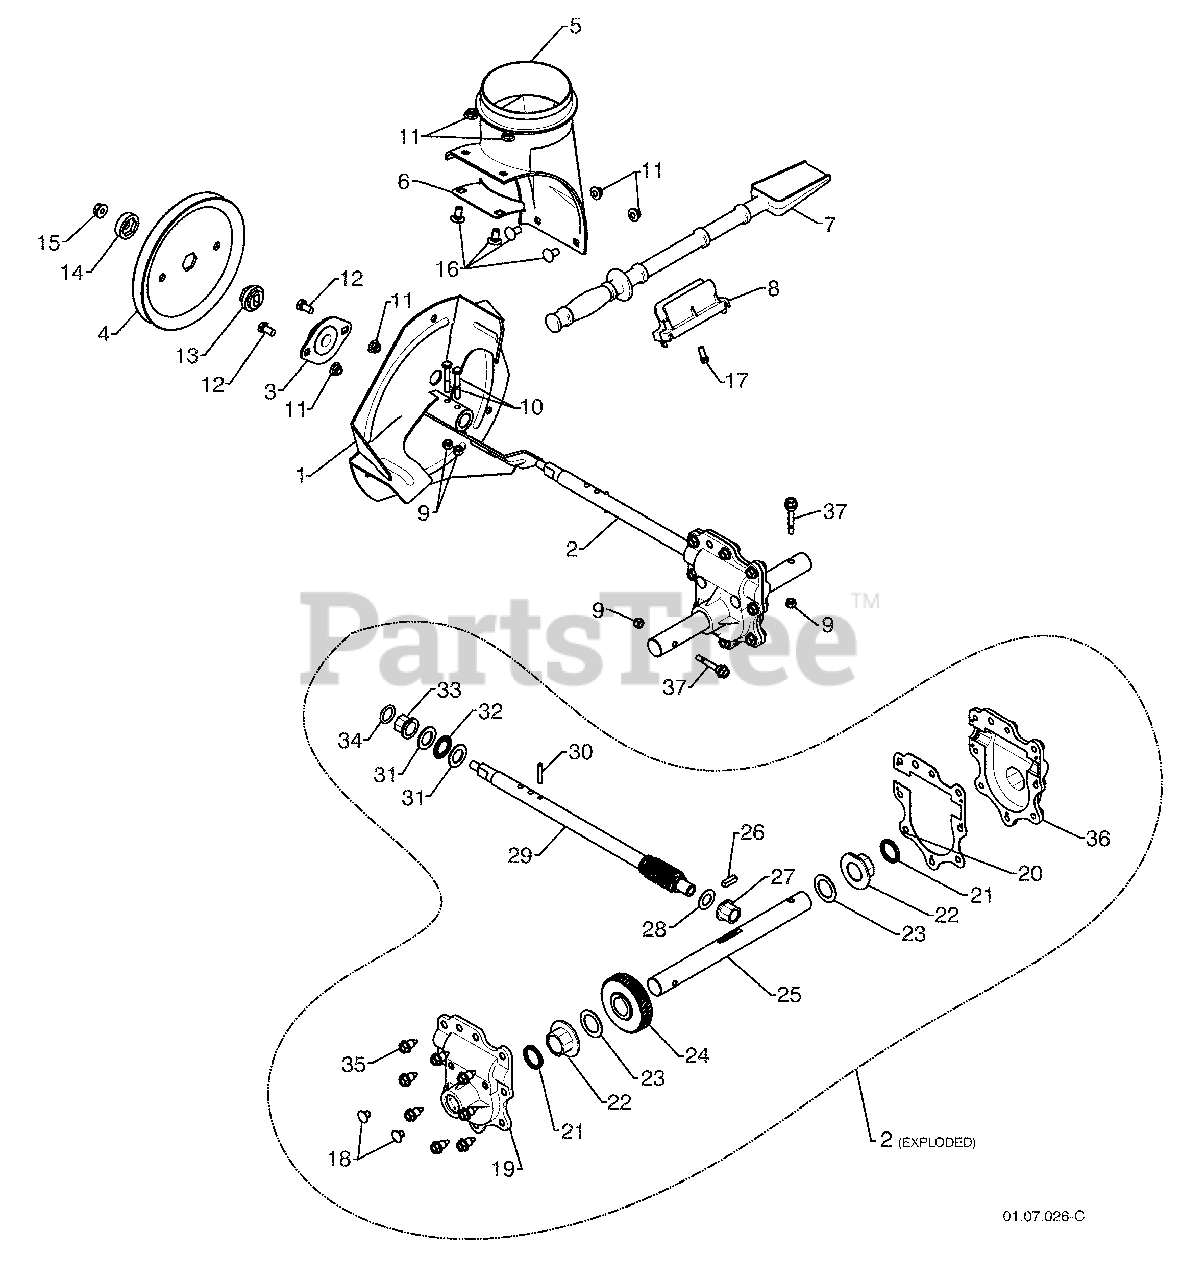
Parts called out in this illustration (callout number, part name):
1	IMPELLER
2	GEARBOX ASSEMBLY
4	IMPELLER PULLEY
5	DISCHARGE BASE
6	CORNER BRACKET
7	CLEAN OUT TOOL
9	NUT 1/4-20
10	SCREW 1/4-20 X .625
11	NUT 5/16-18
12	SCREW 5/16-18 X .625
13	IMPELLER HUB
14	IMPELLER SLEEVE
15	NUT 3/8-16
16	CARRIAGE BOLT
17	SCREW 13-16 X .625
18	PLUG
19	GEARBOX COVER RH
21	SEAL
22	BEARING
23	THRUST WASHER 1.00
24	WORM GEAR
25	AUGER SHAFT
26	SQUARE KEY
27	BEARING
28	THRUST WASHER
29	IMPELLER SHAFT
30	ROLL PIN
31	THRUST WASHER
32	THRUST BEARING
35	SCREW 5/16-18 X .750
36	GEARBOX COVER LH
37	SHEAR BOLT
